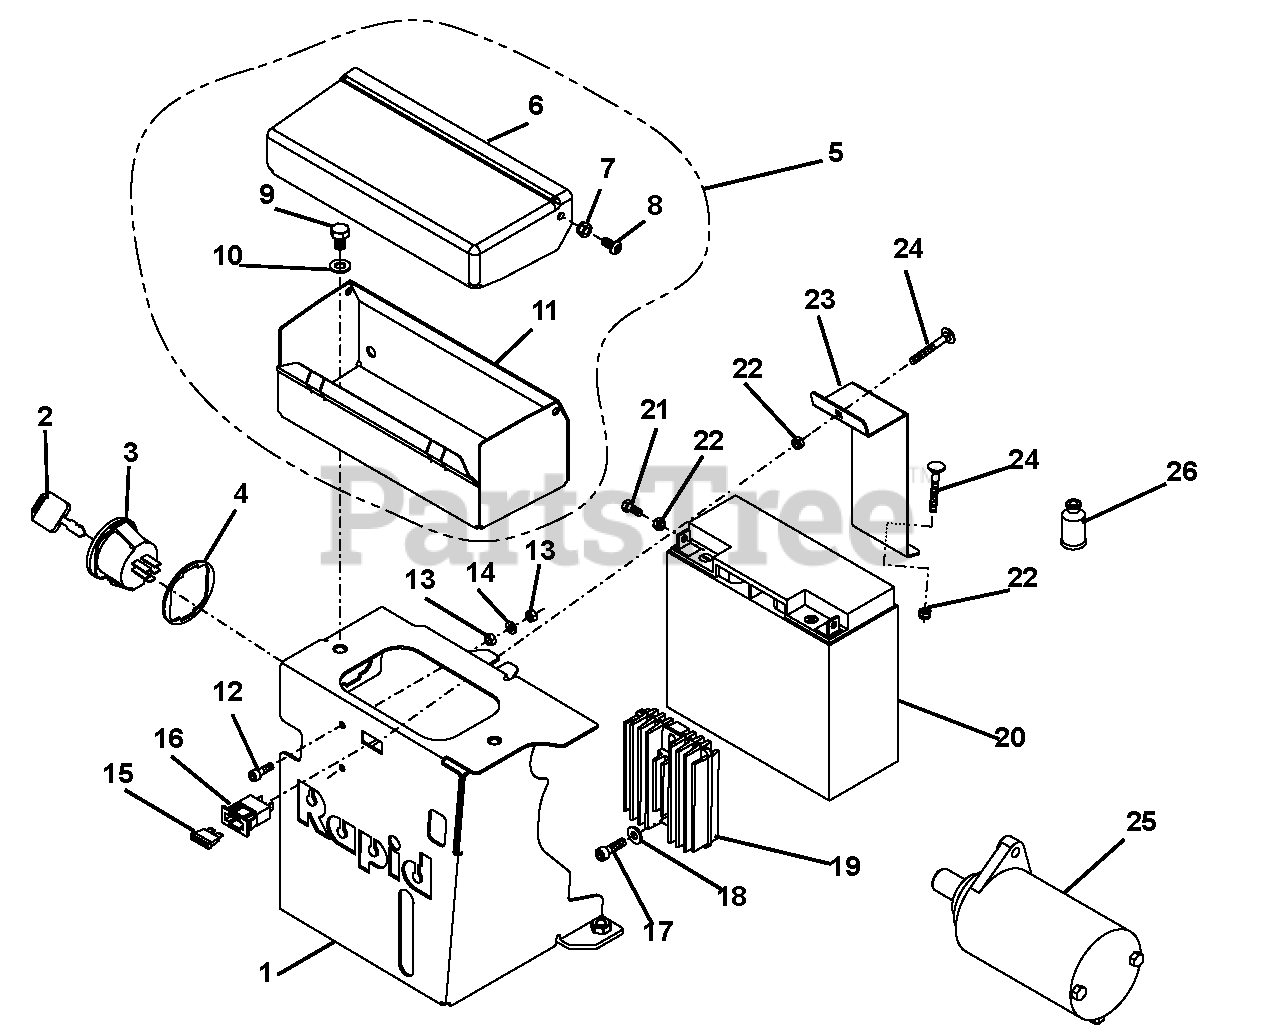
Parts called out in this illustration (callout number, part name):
1	Battery Container
2	Assembly, Key
3	Assembly, Starter Switch
4	Spacer
5	Tool Box Assembly, (Includes 6 - 11)
7	Nut, Lock D985 M6
8	Screw, M6 x 12
9	Bolt, Hex D933 M8 x 12
10	Washer, M8
11	Box, Tool
12	Screw, D912 M5 x 15
13	Nut, Hex D934 M5
14	Washer, M5
15	15A, Fuse
16	Fuse Box
17	Screw, M6 x 20
18	Spacer, 1.03 x 1.38 x .184
19	Regulator, AC
20	Battery, Rapid
21	Bolt, D933 M5 x 12
22	Nut, Lock M5
23	Bow, Fastener
24	Screw, Truss Head, D603 M5 x 40
25	Electrical Starter, Robin
26	Protecting Cap
